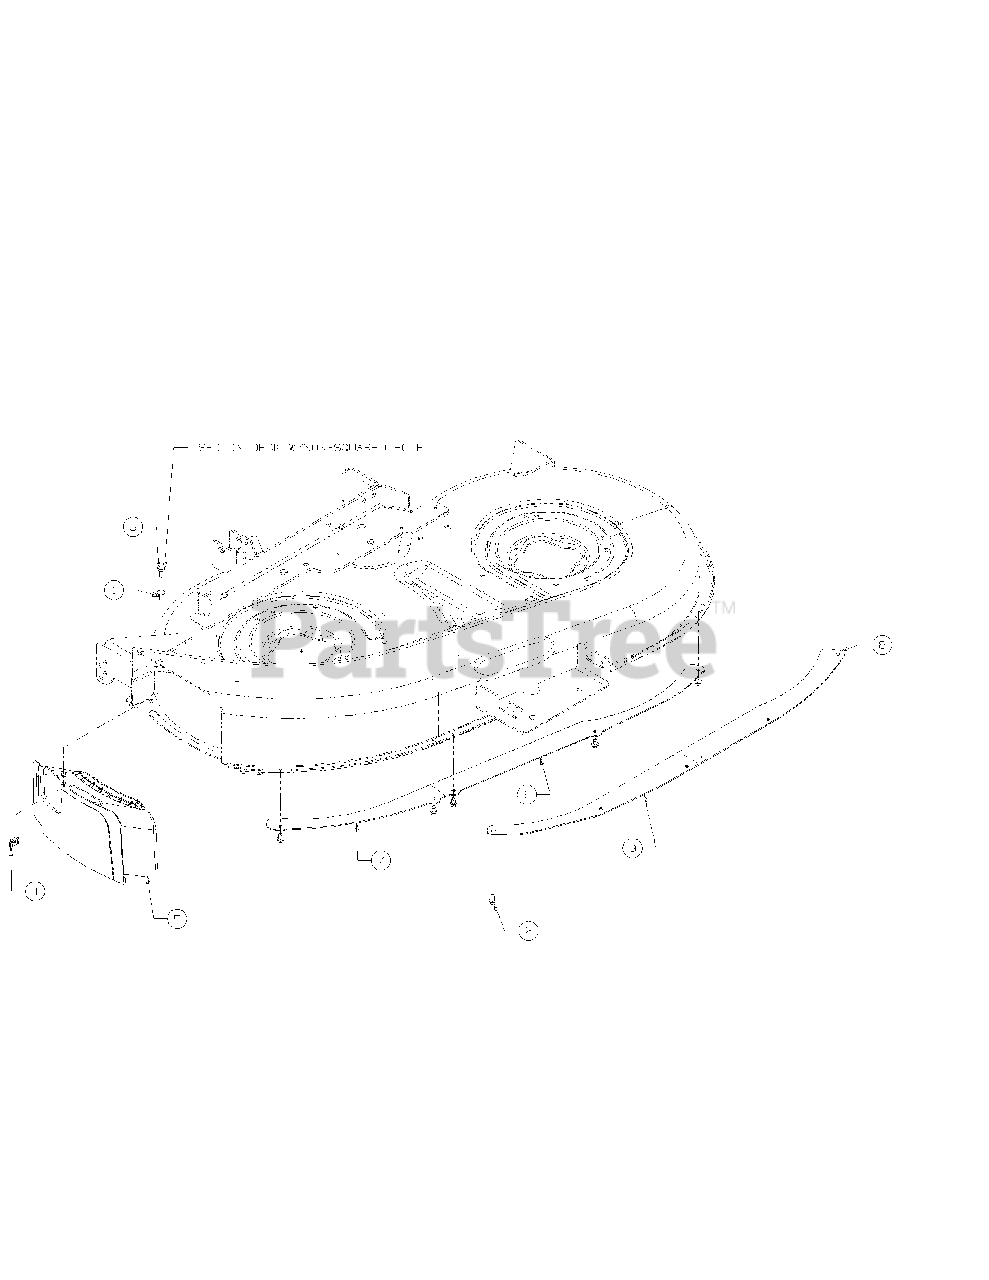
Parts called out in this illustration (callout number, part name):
1	1/4-20 x .6 Carriage Screw
2	1/4-20 x .5 Self-tapping Screws
3	1/4-20 x .6 Hex Screw
4	1/4-20 Plastic Wing Nut
5	Mulch Plug
6	LH Skirt for 42-inch Decks
7	RH Skirt for 42-inch Decks
8	RH Skirt for 38-inch Decks
9	LH Skirt for 38-inch Decks
